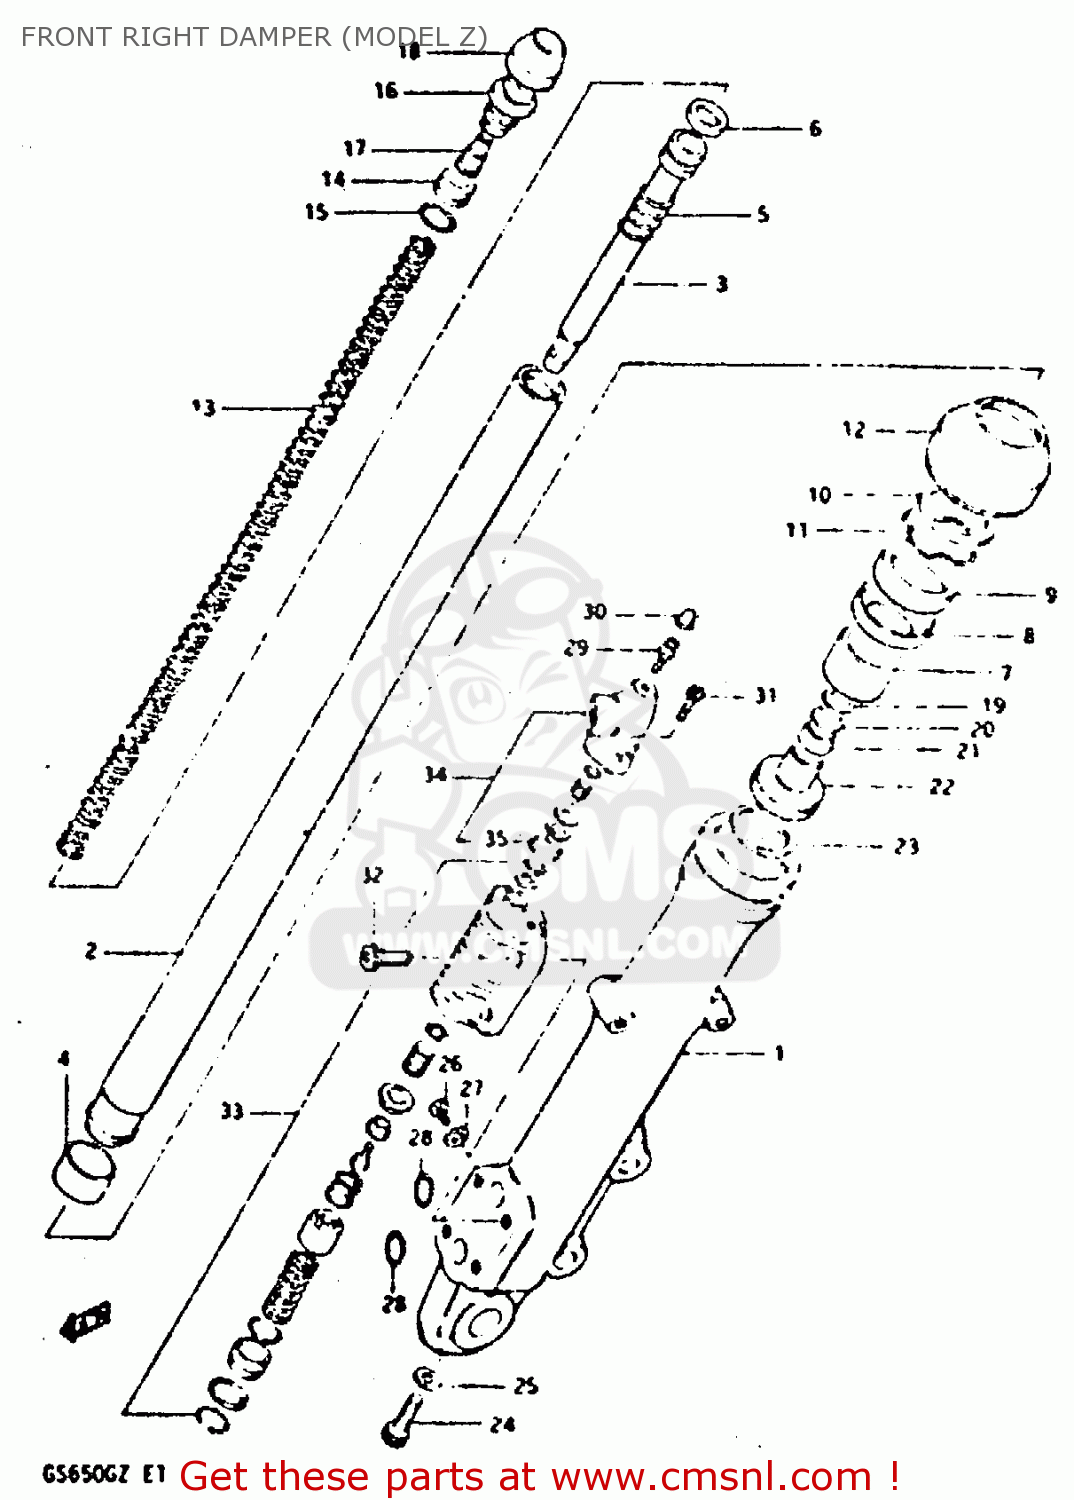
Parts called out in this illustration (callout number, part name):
1	TUBE,FORK,OUTER,RIGHT
2	INNER TUBE
3	CYLINDER
4	PISTON
5	SPRING,FORK REBOUND
6	RING,PISTON
7	GUIDE,FORK INNER TUBE
8	SPACER,SEAL
9	OIL SEAL,FRONT FORK
10	RING,BACKUP
11	CIRCLIP,INNTERNAL
12	DUST SEAL
13	SPRING
14	SEAT,FRONT FORK SPRING
15	O RING
16	CAP,FORK INNER TUBE
17	ADJUSTER,SPRING
18	CAP
19	VALVE
20	SPRING,VALVE
21	VALVE,OIL LOCK PIEACE
22	PIECE,OIL LOCK
23	RING,PISTON
24	BOLT(8X27)
25	GASKET (NAS)
26	BOLT
27	GASKET,DRAIN,PLUG (NAS)
28	O RING,FR FORK
29	BREATHER
30	CAP
31	BOLT
32	BOLT
33	MODULATOR VALVE SET,FRONT
34	MODULATOR VALVE SET,FRONT
35	SEPARATOR,FRONT FORK MODULATOR
